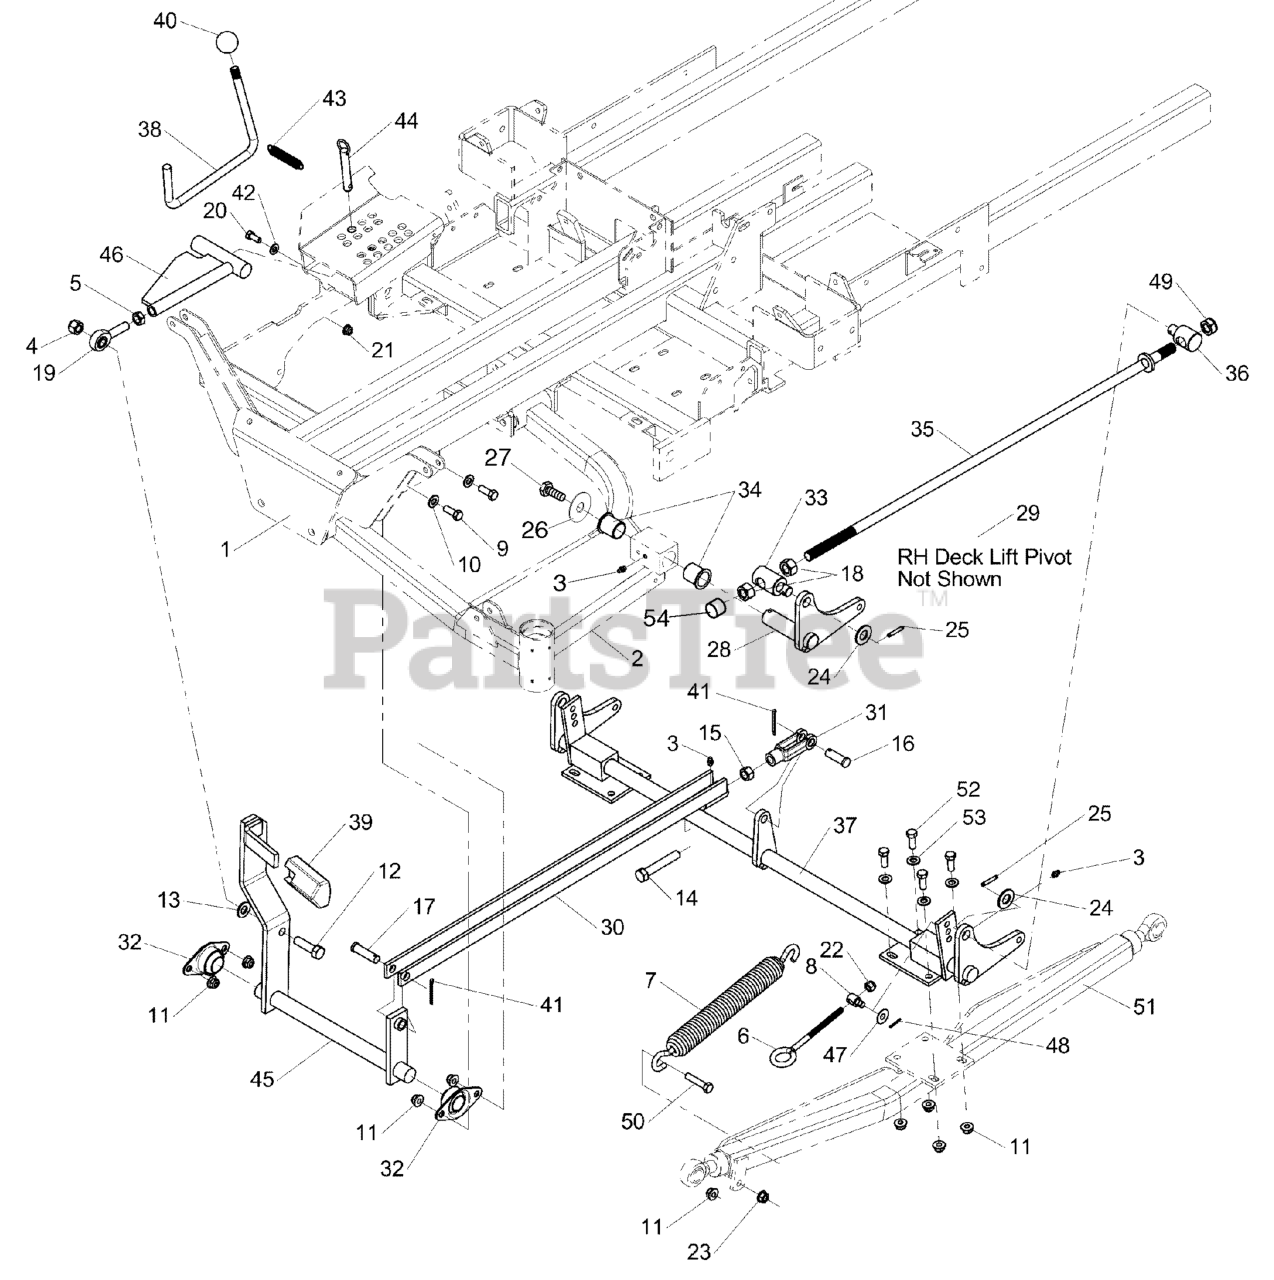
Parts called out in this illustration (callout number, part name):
1	MAIN FRAME
2	CONTROL ARM
3	GREASE FITTING
4	NUT, Hex, Nylon Lock, 1/2-20
5	NUT, 1/2-20 HEX JAM
6	EYE BOLT, 3/8-16 X 6", 1" EYE
7	DECK LIFT SPRING
8	ADJUSTER, BRAKE LINKAGE
9	BOLT, 3/8-16 X 1" GD5 CZ
10	WASHER, 3/8 SAE
11	NUT, 3/8-16 Hex Nylock Flange
12	BOLT, 1/2-20 X 1-3/4" GD8 CZ
13	WASHER, 1/2 SAE
14	BOLT, 1/2-20 X 3-1/2" GD5 YZ
15	NUT, 1/2-20 HEX
16	PIN,CLEVIS, 1/2 X 1 1/2, YZP
17	PIN, CLEVIS, 1/2 X 1-3/4 YZP
18	NUT, 5/8-11 HEX
19	BALL JOINT, 1/2-20, MALE
20	BOLT, 5/16-18 X 3/4 GD5
21	NUT, 5/16-18 HEX NYLOCK FLANGE
22	NUT, 3/8-16 HEX NYLON LOCK
23	NUT, 3/8-16 HEX SERRATED FLANGE
24	WASHER, SHIM, 5/8 X 18 GA YZ
25	PIN, 3/16" X 1-1/4" SPRING
26	WASHER, .390 X 1.50 X .109, YZ
27	BOLT, 3/8-16 X 3/4, PLT W/PATCH
28	PIVOT,DECK LIFT WELD,LEFT
30	WELD, DECK LIFT LINK - RED
31	CLEVIS , 1/2-20, STEEL
32	TRIANGLE BEARING
33	SPRING ROD PIVOT
34	BUSHING, 1.00 X 1.13 X 1.38, PLASTIC
35	ROD, DECK ADJUSTMENT
36	PIVOT, SPRING ROD
37	WELD, DECK LIFT SHAFT - RED
38	WELD, DECK LIFT LOCK ROD - RED
39	PEDAL, Rubber
40	KNOB, PLASTIC, 1/2-13
41	PIN, COTTER, 1/8 X 1-1/4
42	WASHER, 5/16" SAE
43	SPRING, EXTENSION
44	PIN, 1/2 x 3
45	DECK LIFT PEDAL SHAFT - RED
46	DECK ADJUST LINK - RED
47	WASHER, .389 X 1.00 X .020, STAINLESS
48	PIN, 3/32 X 0.750, COT, ZINC/CLEAR
49	NUT, 5/8-11 HEX JAM NYLON LOCK
50	BOLT, 3/8-16 X 1-3/4" GD5 CZ
51	SUSPENSION LINK
52	BOLT, 3/8-16 X 1-1/4" GD5 CZ
53	WASHER, 3/8" GD.9 FLAT
54	CAP, VINYL - .562 X .750 - BLK
